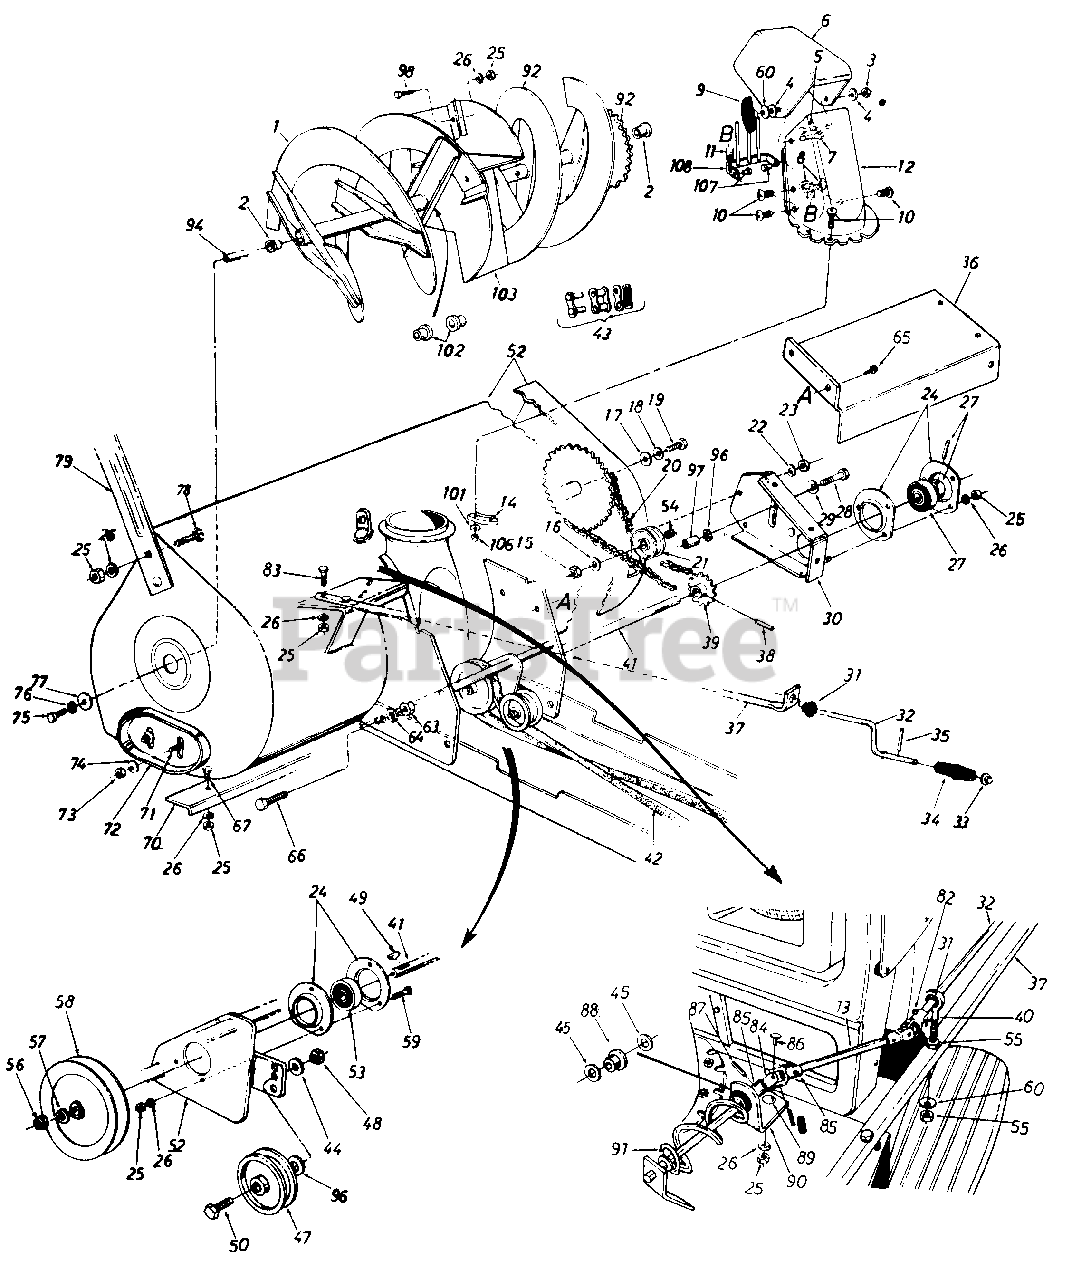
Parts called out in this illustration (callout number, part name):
3	Hex Cent. L.-Nut 5/16-18 Thd.
4	Fl.-Wash. .344' I.D.
5	Truss Mach. Scr. 5/16-18 x .75" Lg.
6	Upper Chute
7	Carriage Bolt 5/16-18 x 1.0" Lg.
8	Hex L-Nut 1/4-20 Thd.
9	Hanc Knob
10	Truss Mach. Scr. 1/4-20 x .75' Lg.
11	Ext. Spring
12	Lower Chute
13	Chute Crank Extension Rod
14	Chute Flange Keeper
15	L.-Nut 3/8-16 Thd.
16	Fl.-Wash.
17	Fl.-Wash.
18	Belleville Wash.
19	Hex Bolt 1/2-13 x 1.00" Lg.
20	#420 Chain 1/2" Pitch x 77 Links
21	Plastic Idler 2.00" O.D.
22	L.-Wash. 1/4" I.D.
23	Hex Nut 1/4-20 Thd.
24	Bearing Housing
25	Hex Nut 5/16-18 Thd.
26	L.-Wash. 5/16" I.D.
27	Self-Aligning Bearing
28	Hex Bolt 3/8-16 x 1.75" Lg.
29	Belleville Wash. 3/8" I.D.
32	Chute Crank .375 Dia. x 34.5" Lg.
33	Push Nut 3/8" Rod
34	Knob (Black)
35	Roll Pin
39	14 Teeth Sprocket Ass'y.
40	Eyebolt 5/16-18 x 3.0" Lg.
41	Drive Shaft
42	"V"-Belt
43	Master Link for #420 Chain
44	L.-Wash. 3/8" I.D.
45	Fl.-Wash..385 I.D. x .62" O.D.
47	Fl.-Idler with Flanges
48	Hex Jam L.-Nut 3/8-16 Thd.
49	#61 Hi-Pro Key 3/16 x 5/8 Dia.
50	Hex Bolt 3/8-16 x 1.75" 4.
52	Spiral Housing Ass'y.
53	Self-Aligning Bearing
54	Sleeve Bearing .50" I.D.
55	Hex Nut 5/16-18 Thd.
56	Hex Nut 3/4-10 Thd.
57	L.-Wash. 3/4" I.D.
58	"V"-Pulley .750" I.D. x 6.00" O.D.
59	Hex Sems Bolt 5/16-18 x .75" Lg.
60	Bell.-Wash. .345" I.D. x .88" O.D.
63	Hex Nut 1/2-13 Thd.
64	L.Wash. 1/2'" I.D. Lg.
65	Hex Wash. Hd. Tap Scr. 1/4-20 x .50" Lg.
66	Hex Bolt 1/2-13 x 2.75" Lg.
67	Carriage Bolt 5/16-18 x .75"
72	Skid Shoe
73	Hex Jam Nut 3/8-16 Thd.
74	Belleville Wash. 3/8" I.D.
75	Hex Bolt 1/2-13 x 1.00" Lg.
76	Belleville Wash. l/2" I.D.
77	Fl.-Wash.
78	Carriage Bolt 5/16-19 x .62" Lg.
82	Cotter Pin
83	Hex Bolt 5/16-18 x 1,50" Lg.
84	Joint Block
85	Joint Bracket Ass'y.
86	Oval Head Rivet
87	Spring Pin Roll 1/8" Dia. x .75" Lg.
88	Nylon 8ushing
89	Carriage Bolt 5/16-18 x .75" Lg.
90	Chute Crank Bracket
91	Chute Crank Ass'y.
96	Flat Washer
97	Idler Spacer
98	Carriage Bolt 5/16-18 x .75" Lg.
101	Fl.-Wash. 1/4" I.D.
102	Plastic Bushing
107	Shld. Nut 1/4-20 Thd.
05139A-0637	BLADE-GUIDE (DRIFT - POWDER BLACK (0637)
05139A-0638	BLADE-GUIDE (DRIFT - MTD/TROY-BILT RED (0638)
05139A-0662	BLADE-GUIDE (DRIFT - OYSTER GRAY (0662)
05139A-0665	BLADE-GUIDE (DRIFT - YARDMAN GREEN (0665)
05139A-0674	BLADE-GUIDE (DRIFT - YARDMAN YELLOW (0674)
05139A-0716	BLADE-GUIDE (DRIFT - CUB YELLOW-99 (0716)
